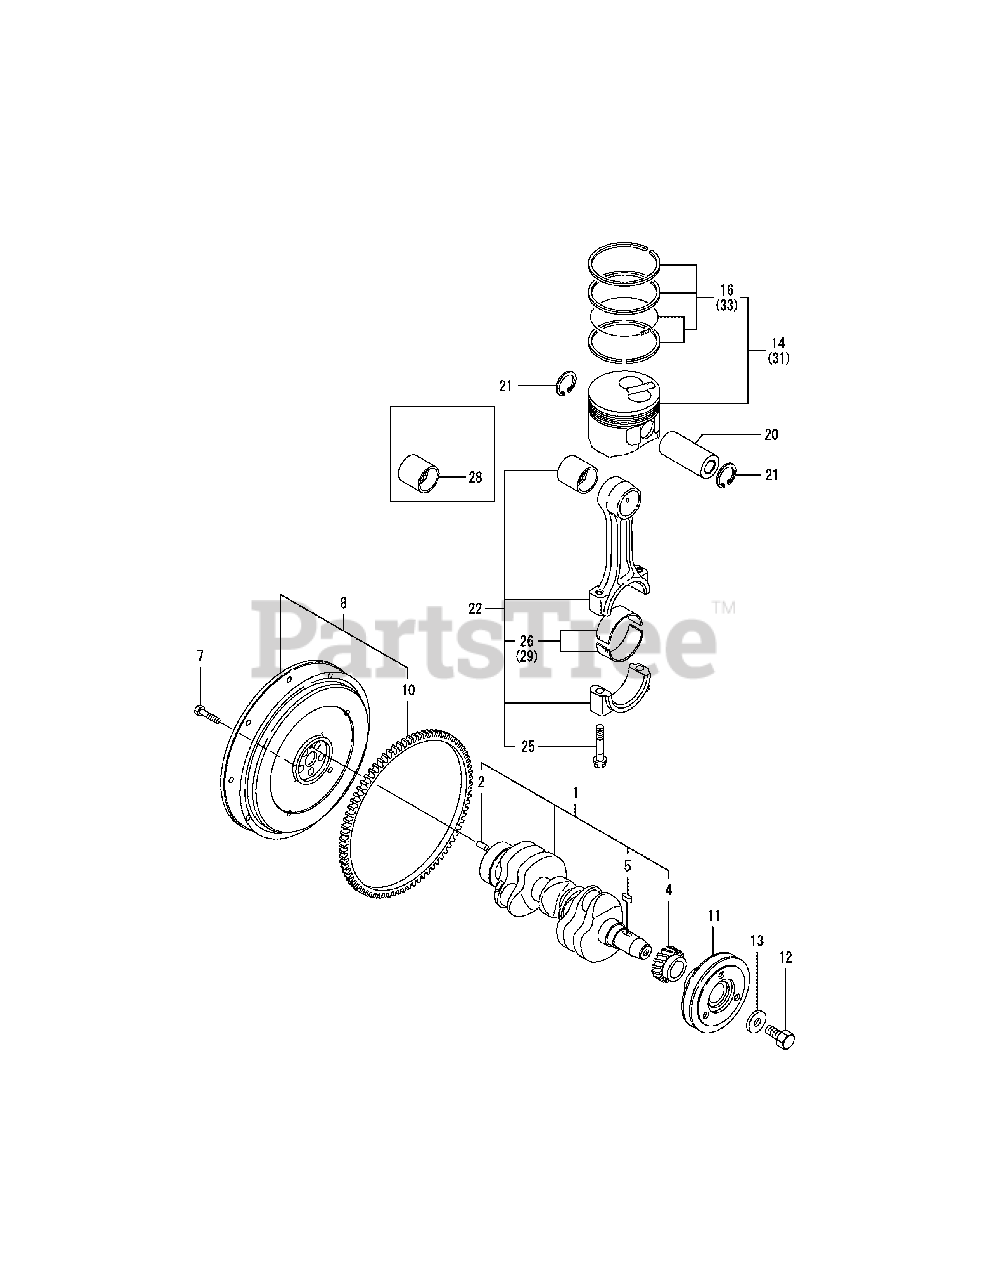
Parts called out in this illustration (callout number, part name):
1	Crankshaft Assembly
2	Parallel Pin 8 x 16
4	Gear, Crankshaft
7	Bolt, Flywheel
8	Flywheel Assembly
11	V-Pulley, Crankshaft
12	Bolt M12 x 1.25, Flange
14	Piston Assembly
22	Rod Assembly, Connecting
25	Bolt, Connecting Rod
26	Metal Assembly, Crank Pin
28	Bush, Piston Pin
31	Piston Assembly
